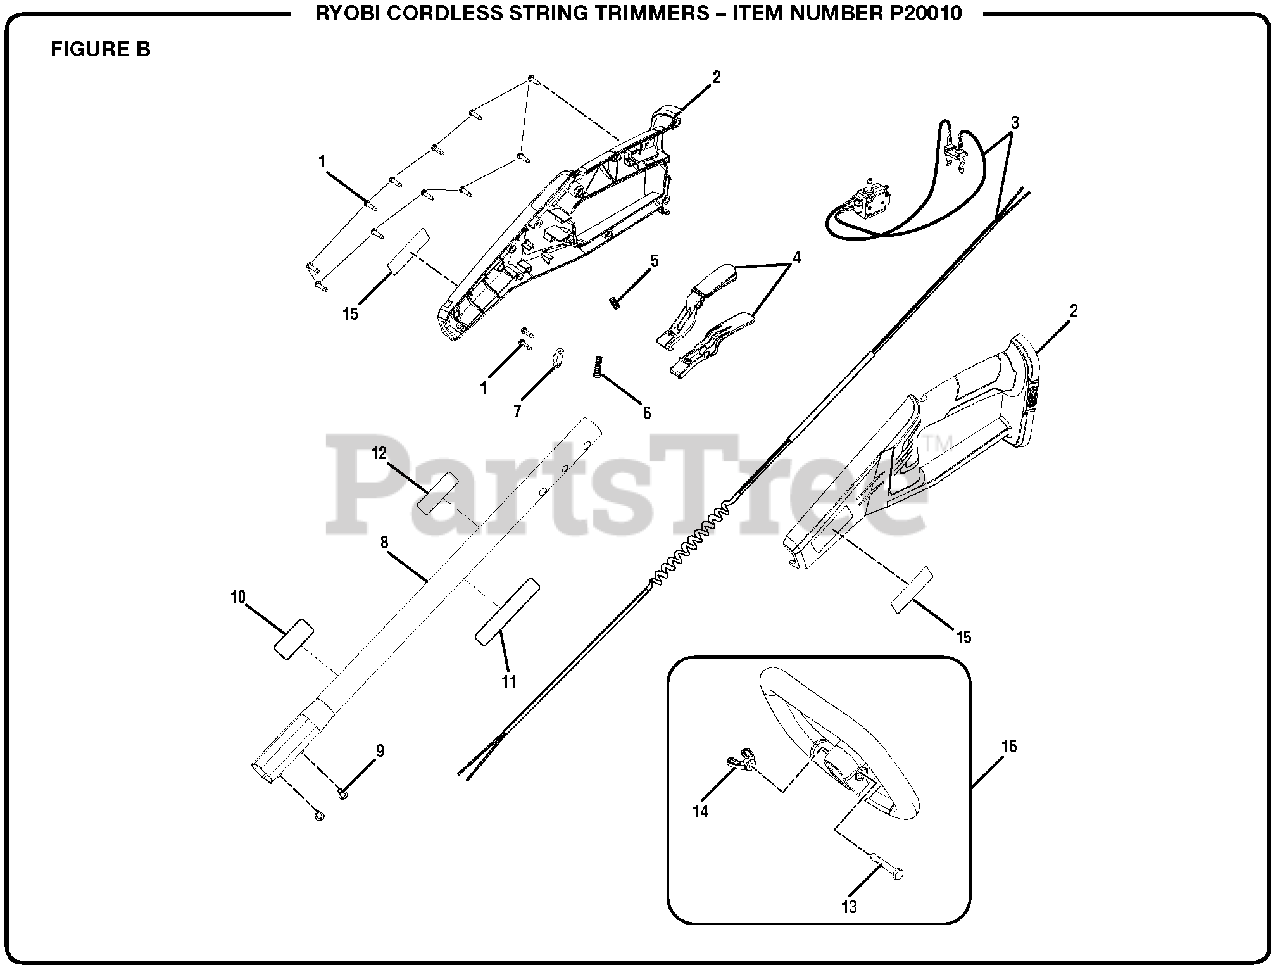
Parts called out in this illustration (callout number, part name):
1	Screw (M4 x 18 mm, Torx Socket Hd.)
2	Handle Housing Assembly w/Label
3	Switch, Contact Plate Assembly and Wire Harness
4	Switch Trigger and Lock-Out Assembly
5	Lock-Out Compression Spring
6	Trigger Compression Spring
7	Strain Relief Plate
8	Upper Tube Assembly
9	Screw (M5 x 10 mm)
10	Data Label
11	Icon Label
12	Warning Label (Upper End)
13	Screw (1/4-20 x 40 mm, Hex Cap Hd.)
14	Wing Nut (1/4-20)
15	Logo Label (Upper End)
16	Auxiliary Handle Assembly
